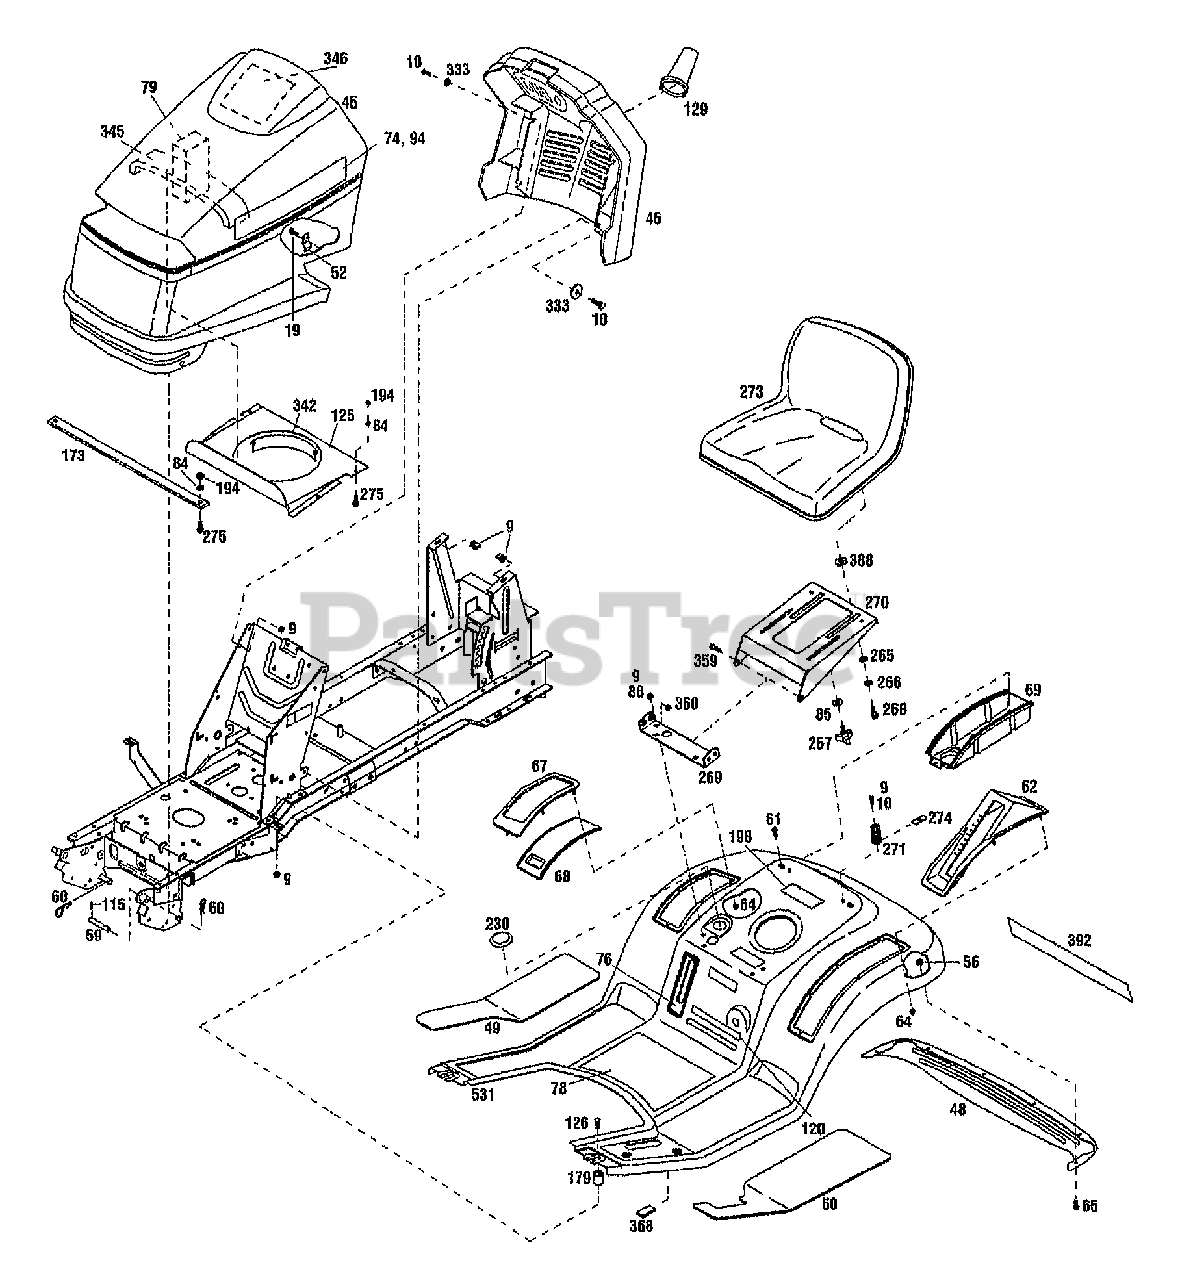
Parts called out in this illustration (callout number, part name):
9	NUT-HFLK 5/16-18 ZP
10	SCR-HHC 5/16-18X.75 GR 5 ZP
19	SCR-SPECIAL #10
45	HOOD-TRACTOR
46	CONSOLE
48	TRIM-FENDER REAR
49	PAD-FOOT RH
50	PAD-FOOT LH
52	LATCH
56	NUT-HF/LK 1/4-20 ZP
57	NUT-SELF RETAIN 5/16-18
59	PIN-HOOD PIVOT
60	PIN-HITCH .125X2.56 ZP
61	SCR-LOCK
62	COVER-LIFT HANDLE {13103,13104}
63	DECAL-AMERICAN LEGEND-LRG
64	NUT-SELF THREADING
65	SCR-HH 1/4-20X.625
67	TOP-STORAGE COVER
68	COVER-CONTAINER
69	CONTAINER-STORAGE
74	DECAL-LOGO LH
76	DECAL-FUEL LEVEL
78	TUNNEL {13103,13104}
78	DECAL-TUNNEL {13105}
79	BLOCK-SEALING {13105}
84	WASHER-LK .25 ZP {13103,13104}
84	WASHER-LK .25 ZP {13105}
85	WASHER-FLAT 3/8 SAE
88	SCR-CARR 5/16-18X.62 G2 ZP
94	DECAL-LOGO RH
115	PIN-ROLL .188X1.0
120	DECAL-HGT INDICATOR
125	SHIELD-HEAT UPPER {13105}
126	SCR-CARR 5/16-18X.75
129	COVER-STEERING
133	WASHER-1.5X.343X.104
173	STRAP-HOOD {13103,13104}
179	SPACER-TUBULAR
194	NUT-HEX 1/4-20 ZP {13103,13104}
194	NUT-HEX 1/4-20 ZP {13105}
198	DECAL-FUEL
230	PLUG 2.50
265	WASHER-1.06X.51X.09 NYLON
266	WASHER-BOW .74X.52X.01
268	SCR-SHLDR 3/8-16X.25 G5ZP
269	BRKT-SUPPORT SEAT
270	SUPPORT-SEAT
271	SPRING-COMPRESSION
273	SEAT-HIGH BACK
274	BRKT-SPRING HOLD DOWN
275	SCR-HH 1/4-20X.625 G5 ZP {13103,13104}
275	SCR-HH 1/4-20X.625 G5 ZP {13105}
333	WASHER-1.5X.343X.104
342	GASKET-HEAT SHIELD {13105}
345	STRIP-SEALING {13105}
346	DECAL-SERVICE
359	SCR-HH 3/8-16X.88 G5 ZP
360	NUT-H/LK 3/8-16
388	WASHER-FLAT
392	DECAL-MODEL {13103}
392	DECAL-MODEL {13104}
392	DECAL-MODEL {13105}
531	FENDER-REAR {13103,13104}
531	FENDER-RED W/DECALS {13105}
600	PAINT-BLACK SPRAY
601	PAINT-RED SPRAYCAN POWDER
